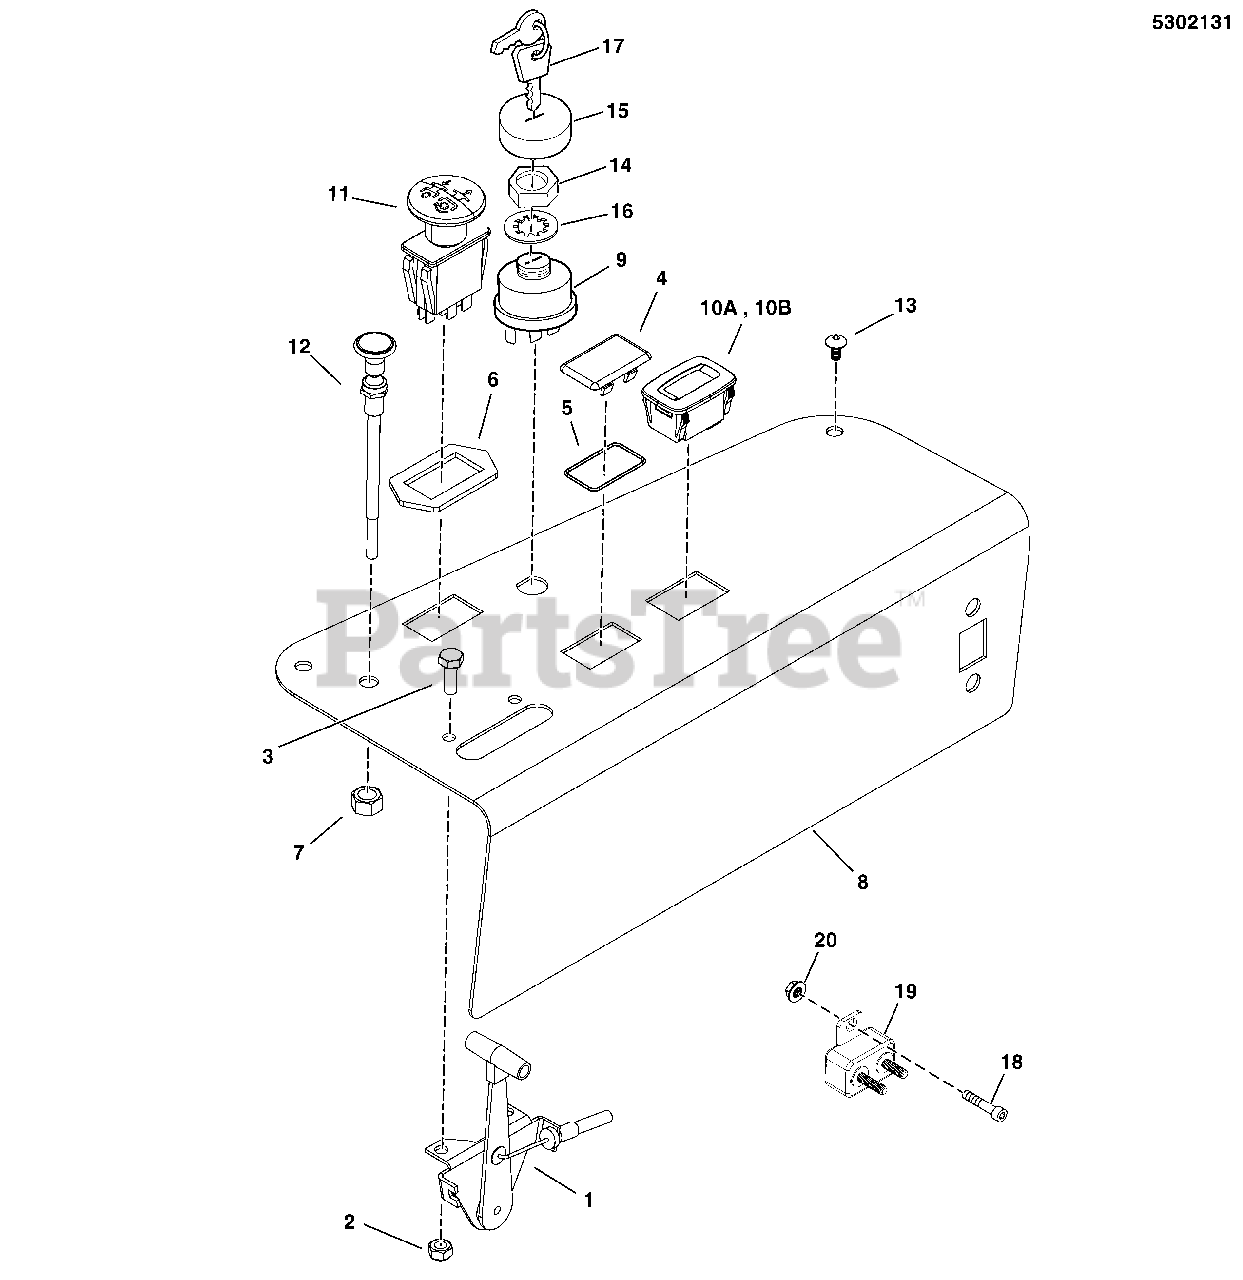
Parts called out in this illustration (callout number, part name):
1	CABLE, THROTTLE CONTROL, 38
2	HUT, HEX NYLON LOCK, 1/4x20"
3	BOLT, 1/4"-20 X 3/4" GD5 YZ
4	PLUG, .820X1.44 HOLE, BLACK PLASTIC
5	O-RING, 7/8" ID X 1/16" W
6	RING, SWITCH RETAINER
7	NUT, 3/8-24 HEX (SV)
8	PLATE, CONTROL PANEL - BLACK
9	SWITCH ASSEMBLY, Ignition Indak No Keys/Hdwr
11	SWITCH, BLADE ENGAGEMENT
12	CABLE, Choke Control, 47"
12	CABLE, CHOKE CONTROL, 39.5"
13	SCREW, ALLEN HEAD 1/4-20 X .500 ZINC PHOS
14	NUT, 5/8-32 Hex Flange (Ignition Switch Die Cast)
15	COVER, For Ignition Switch, Plastic
16	LOCKWASHER-INTERNAL TOOTH, .625 THIN BLK (SV)
17	KEYS, Blister Pk (KIDS+MWRS DON'T MIX) English/Spanish (set of two, one coated)
18	SCREW, ALLEN HEAD 1/4-20 X .500 ZINC PHOS
19	BREAKER-CIRCUIT 12VOLT 20AMPS W/TAB
20	NUT, Hex, Serrated Flange, 1/4-20
